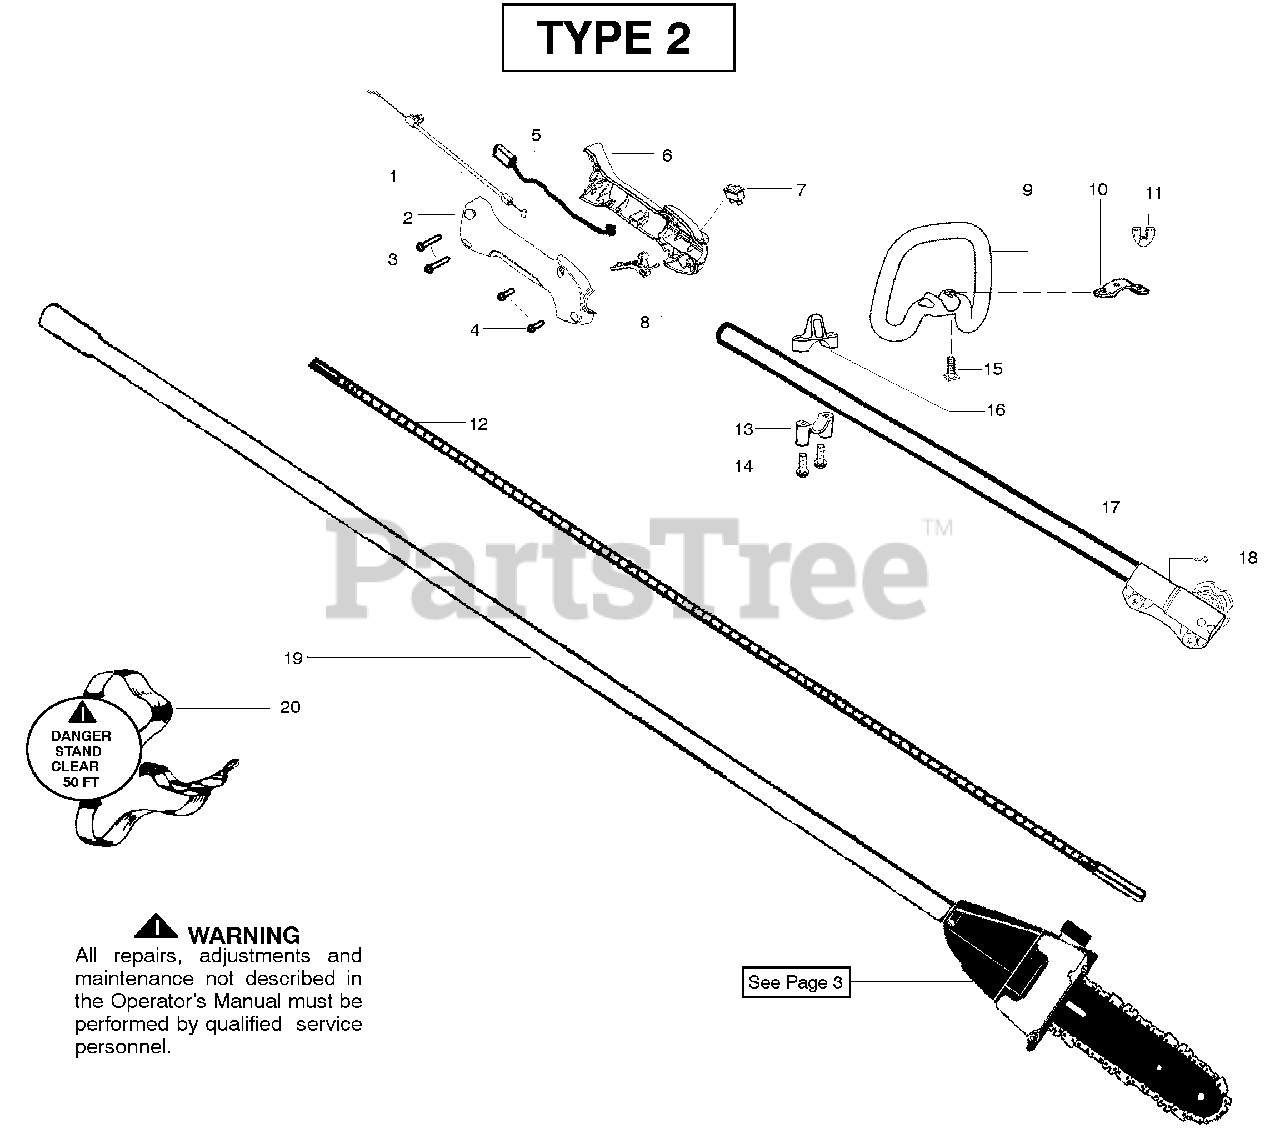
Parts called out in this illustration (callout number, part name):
1	Assy-Throttle Cable
2	Hsg.-Throttle right
5	Assy-Wire
6	Hsg. - Throttle left
7	Kit-Switch
8	Trigger
9	Assy-Handle
10	Clamp-Handle
11	Wingnut
12	Flex-Lower
13	Clamp-Lower
16	Clamp-Upper
17	Kit-Upper Shaft
19	Assy-Driveshaft
20	Assy-Shoulder Strap
